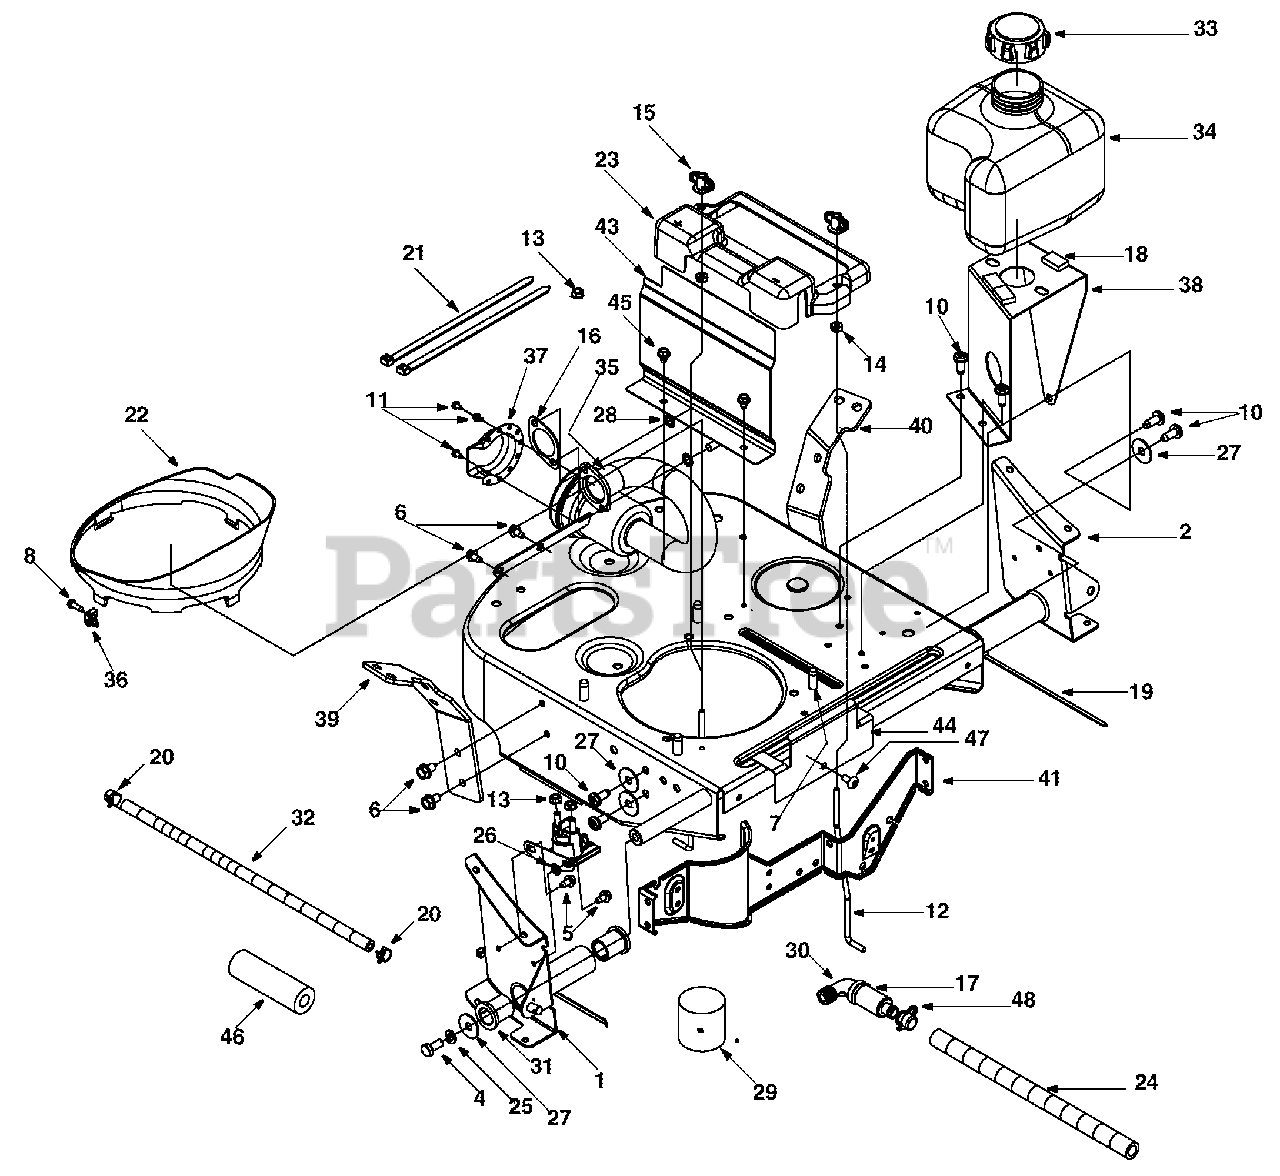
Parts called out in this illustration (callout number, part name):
5	TT Screw 1/4-20 x 0.5"
6	TT Screw 5/16-18 x 0.625"
7	TT Sems Screw 3/8-16 x 1.0"
8	T Screw #10-32 x 0.625"
10	TT Screw 5/16-18 x 0.75"
11	AB Screw 8-18 x 0.375"
12	Battery Hold -Down Rod
13	Sems Nut
14	Hex Lock Nut 1/4-20
15	Wing Nut
16	Exhaust Gasket
17	Oil Drain
18	Foam Tape: 0.625 x 0.25 thk.
19	Cable Tie
20	Hose Clamp
21	Cable Tie
22	Plen
23	Battery Cover
24	Oil Drain Hose
25	Lock Washer 5/16
26	External Lock Washer
27	Flat Washer
28	Lock Washer 1/4
29	SAE 30W Oil
30	Elbow Fitting
31	Flange Bearing
32	Fuel Line Hose
33	Fuel Cap
34	Fuel Tank
35	Muffler
36	Clamp Casing: Throttle
37	Muffler Deflector
43	Heat Shield
44	Bracket
46	Fuel Hose Insulation
47	Trus. Screw 1/4-14 x 0.625"
48	Oil Drain Cap
